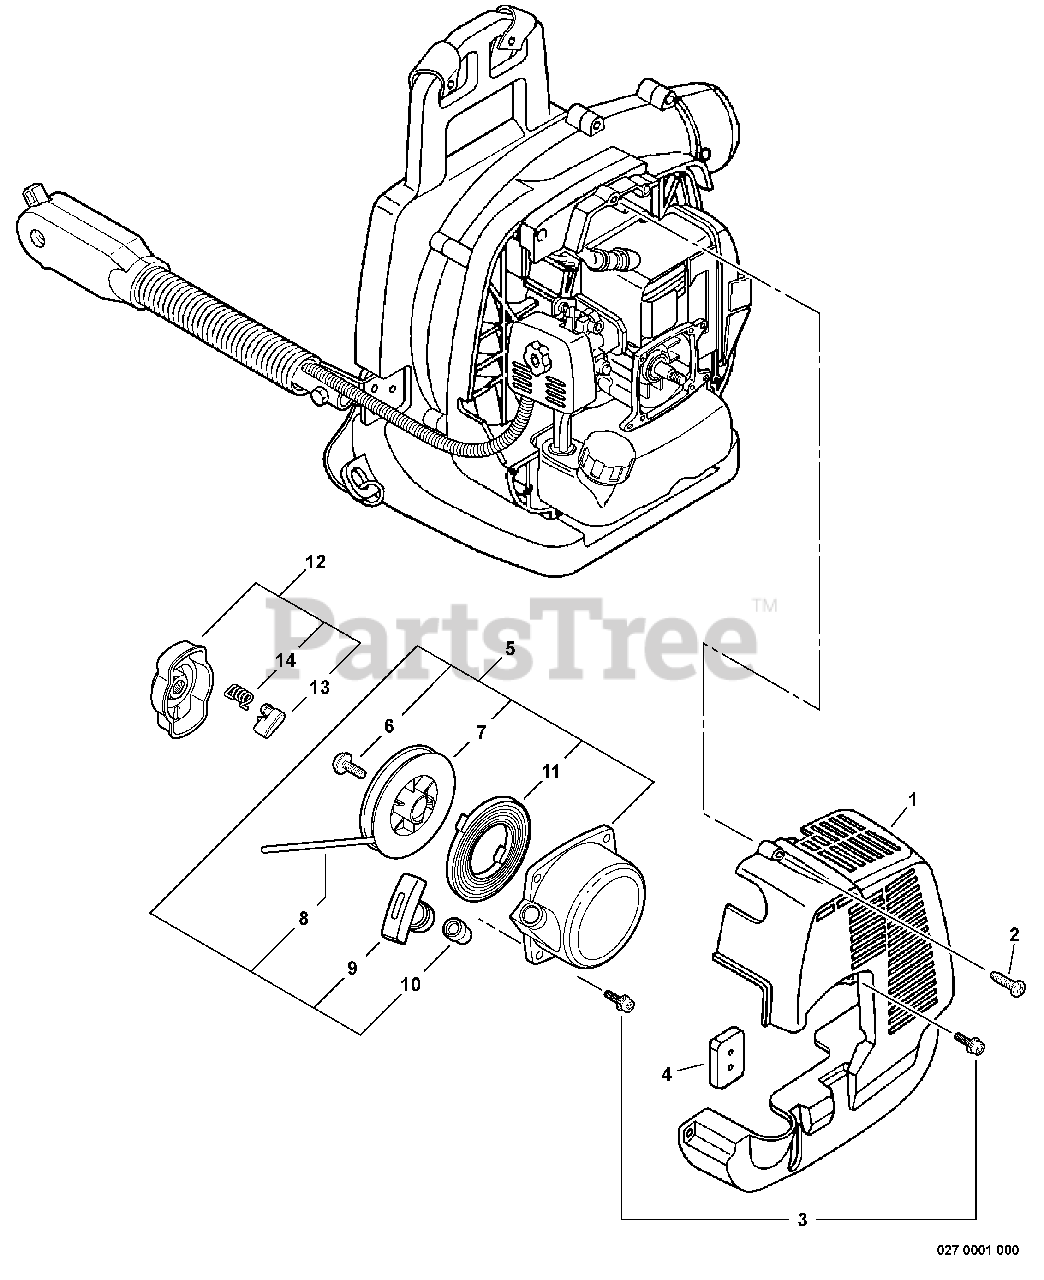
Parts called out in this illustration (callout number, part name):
1	COVER, ENGINE
2	SCREW - 5X20 -- TAPPING
3	SCREW - 4X16
4	CUSHION, FUEL TANK - FRONT
5	STARTER ASSY
7	REEL, ROPE
8	ROPE, STARTER - 3.5X960
9	GRIP, STARTER
10	GUIDE, ROPE
11	SPRING, REWIND
12	STARTER PAWL ASSY
13	PAWL, STARTER - BLACK
14	SPRING, RETURN
